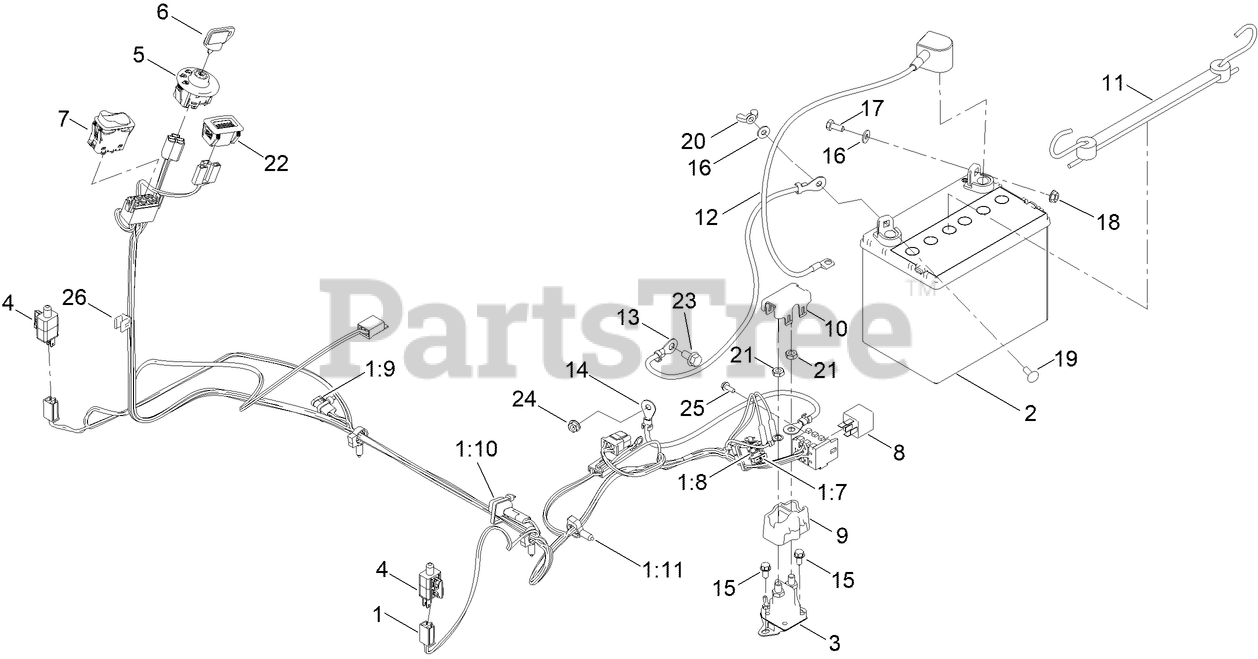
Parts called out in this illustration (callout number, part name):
1	HARNESS-WIRE, MAIN
1:7	FUSE-BLADE, 15 AMP
1:8	FUSE-BLADE, 25 AMP
1:9	CONNECTOR-MOLDED, 1F,1M
1:11	CLIP-TUBING, HARNESS
2	BATTERY- WET, 12V, 300 CCA
3	SOLENOID
4	SWITCH
5	SWITCH-IGNITION
6	KEY-IGNITION
7	SWITCH-ROCKER, ON-NONE-ON
9	COVER-SOLENOID
10	CAP-SOLENOID
11	HOLDDOWN-BATTERY
12	CABLE-BATTERY,RED
13	CABLE-BATTERY, BLACK
14	CABLE-BATTERY, POSITIVE
15	SCREW-HWH
16	WASHER
17	SCREW-HH
18	NUT-HF
19	BOLT-CARR
20	NUT-WING
21	NUT-HJ
22	HOUR METER
23	SCREW-HHF
24	NUT-HF
25	SCREW-TAPTITE
26	CLIP-EDGE W/TIE, PERPENDICULAR
